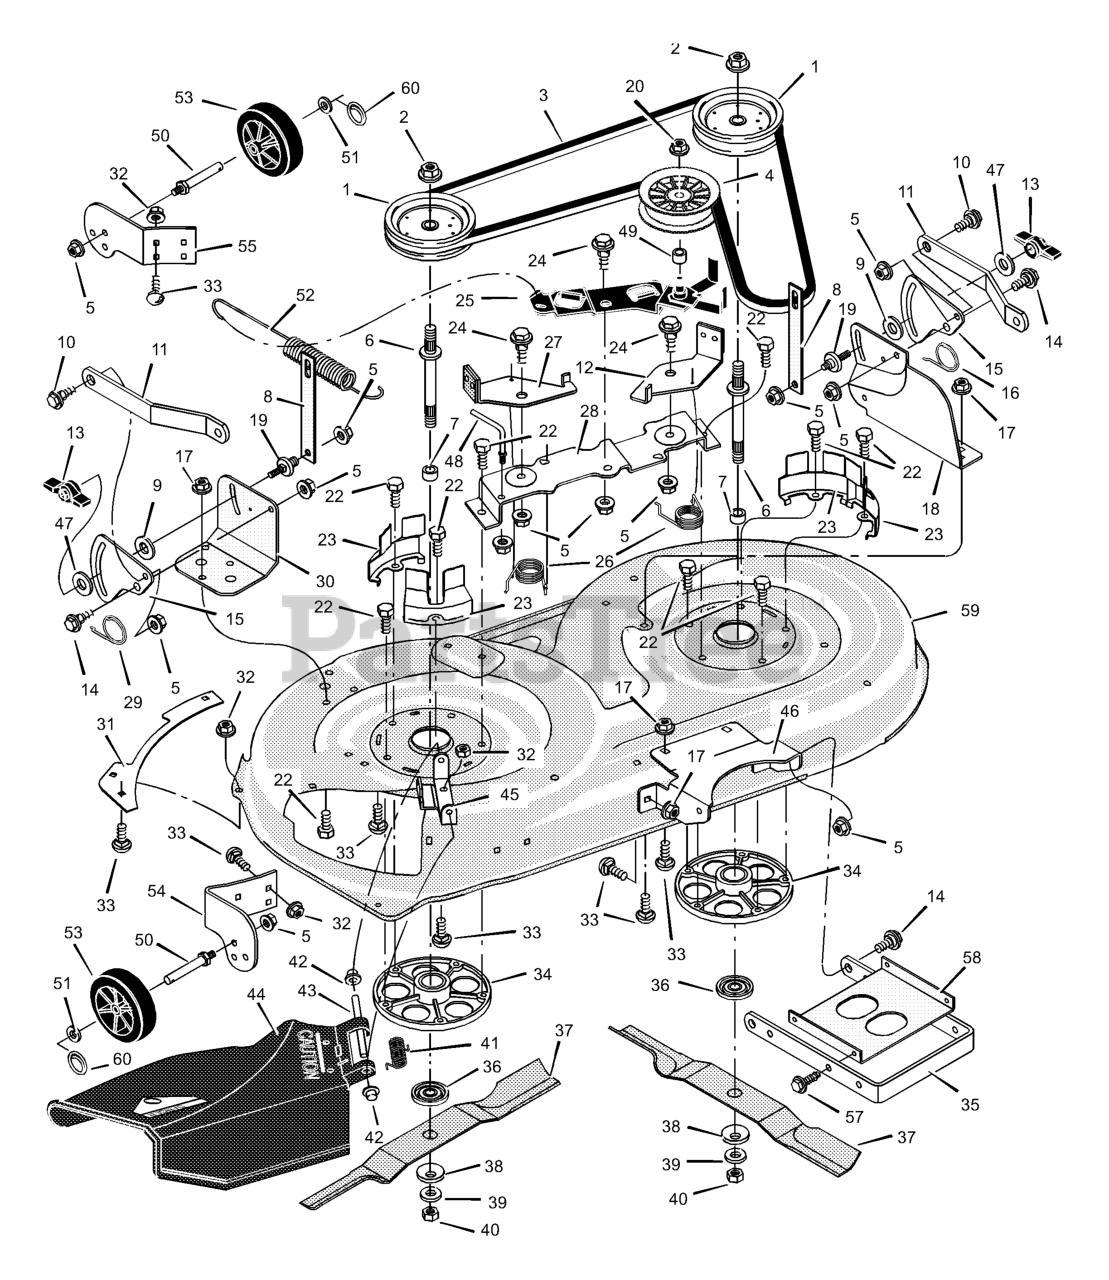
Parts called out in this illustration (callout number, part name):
1	Pulley, Jackshaft
2	Nut, Hex
3	Belt, Mower Drive
4	Pulley, Idler
5	Nut, Flange
6	Jackshaft
8	Link, Lift
9	Pad, Friction
10	Bolt, Shoulder
11	Bracket, Suspension
12	Pad Assembly, Left Brake
13	Knob
14	Bolt, Shoulder
15	Plate, Suspension
17	Nut, Flange
18	Bracket, Suspension
19	Pin, Hanger
20	Nut, Flange
22	Bolt
23	Cover, Pulley
24	Bolt, Shoulder
25	Arm, Idler
27	Pad Assembly, Right Brake
28	Bracket, Brake
30	Bracket, Suspension
32	Nut, Flange
33	Bolt, Carriage
34	Mandrell Housing
35	Bracket, Suspension
36	Adapter, Blade
42	Cap, Push On
43	ROD, Deflector
44	Deflector Assembly
45	Bracket, Deflector Hinge
46	Bracket, Front Hanger
48	Guide, Belt
50	BOLT, Gauge Wheel
52	Spring, Extension
53	Wheel, Gage
54	Bracket, Right Wheel
55	Bracket, Left Wheel
58	Stiffener
59	Housing, Blade, Complete (NO LONGER AVAILABLE)
59	Housing, Blade (Housing Only)
60	Ring, Locking
